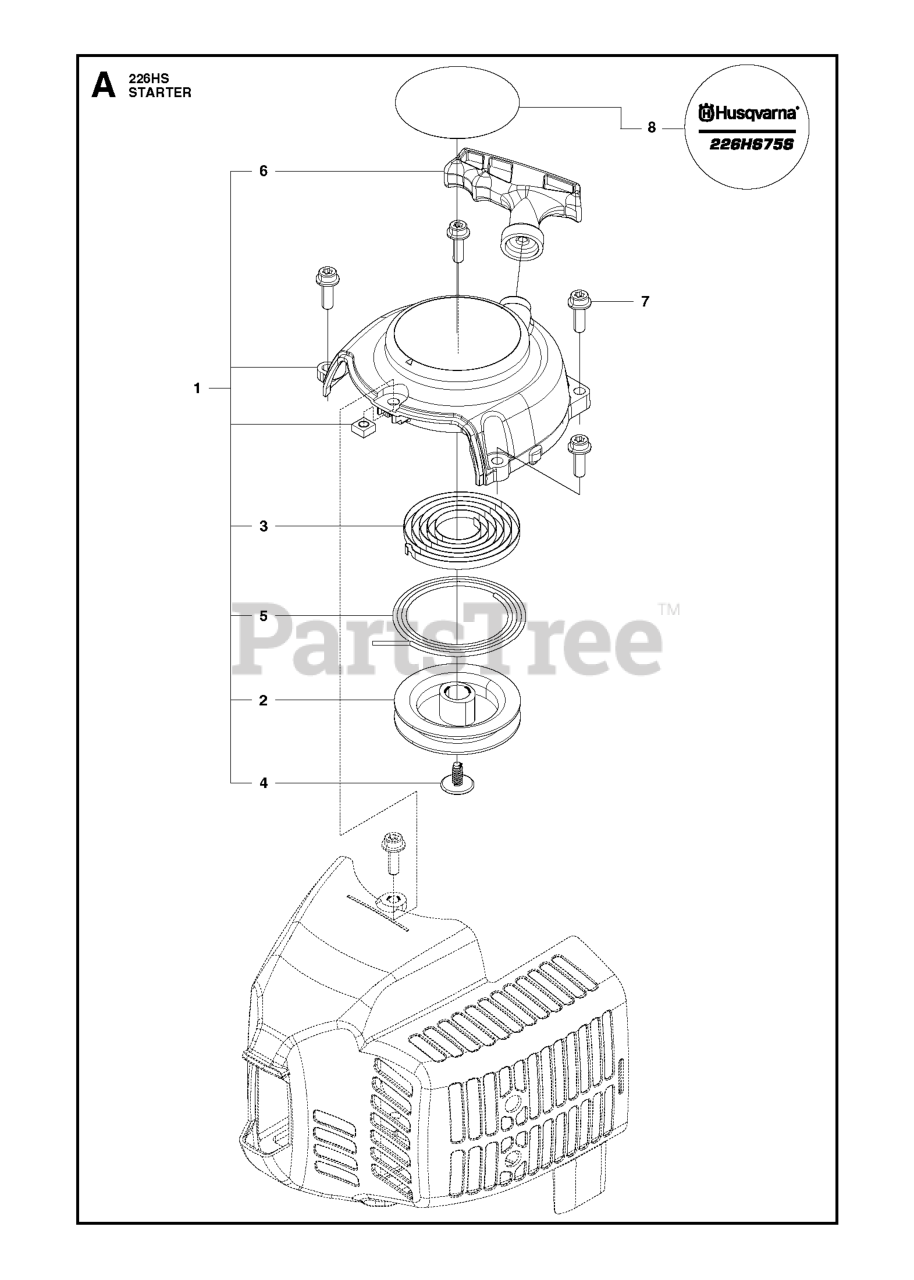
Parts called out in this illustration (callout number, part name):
1	RECOIL ASSY
4	SCREW
8	LABEL,RECOIL
